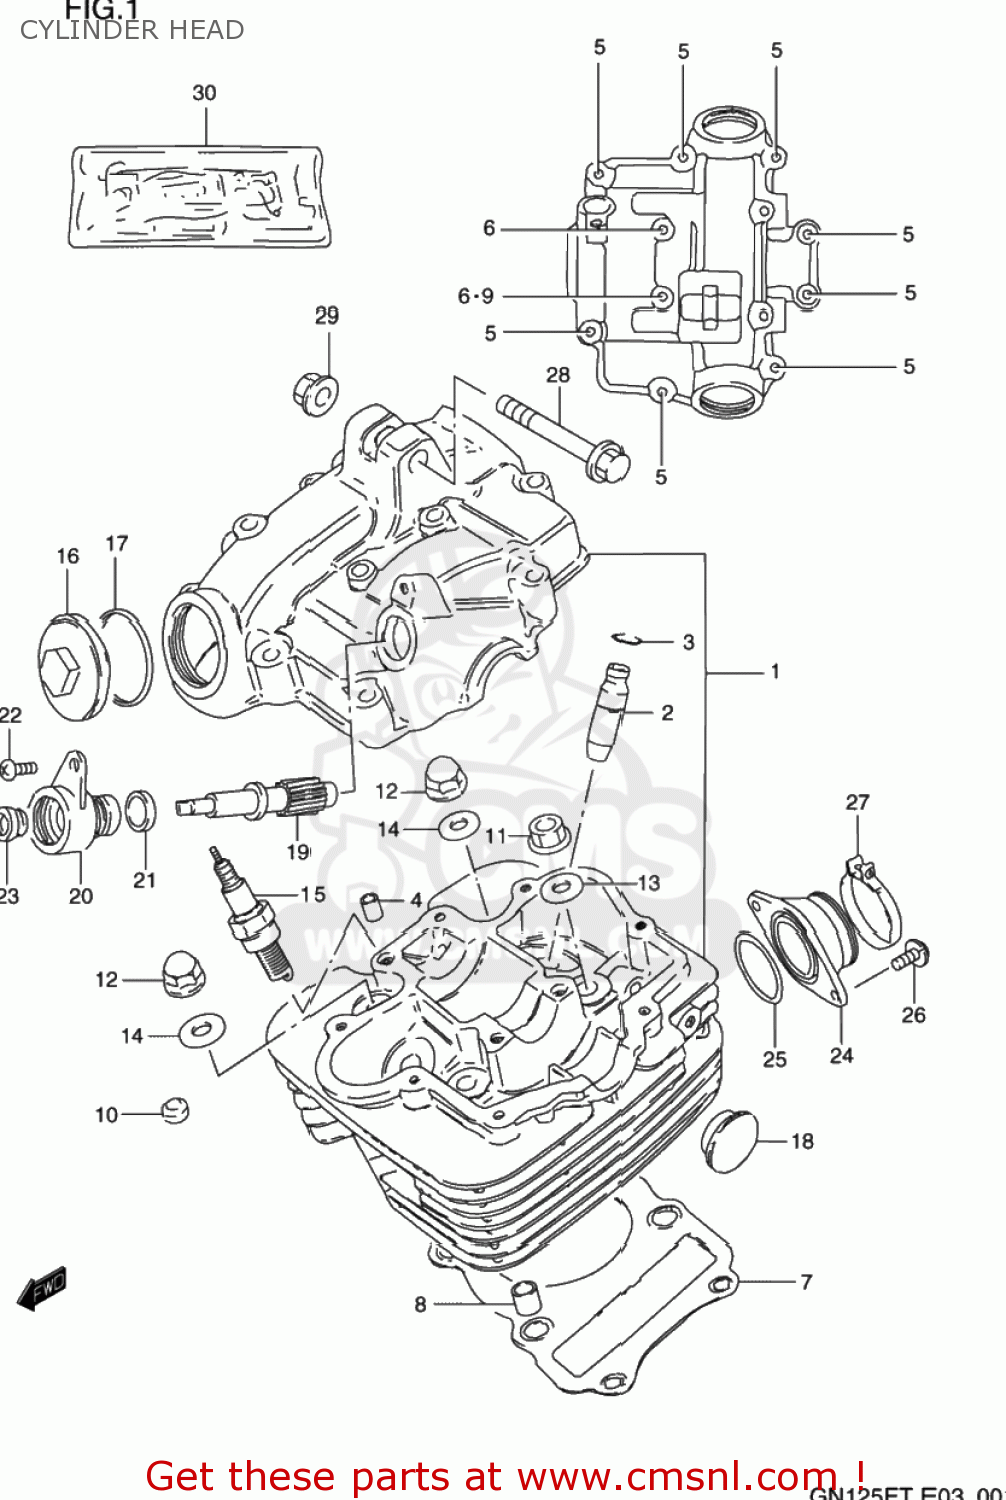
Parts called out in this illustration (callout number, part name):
1	HEAD ASSY,CYLINDER
2	GUIDE,VALVE
3	RING,SNAP
4	PIN(6.2X8X11)
5	BOLT
6	BOLT
7	GASKET,CYLINDER HEAD (NAS)
8	PIN
9	GASKET(5.8X13X1.2) (NAS)
10	PAD,CYLINDER HEAD
11	NUT
12	NUT
13	WASHER(8.5X19X2.3)
14	GASKET (NAS)
15	SPARK PLUG D8EA
16	CAP,INSPECTION HOLE
17	O RING(D:3,ID:29.5)
18	PLUG(OD:22.5)
19	GEAR,TACHOMETER DRIVEN
20	SLEEVE,TACHOMETER DRIVE GEAR
21	SEAL,TACHOMETER DRIVEN
22	SCREW(5X12)
23	SEAL,OIL(5X12X8)
24	PIPE,INTAKE
25	O RING(D:2.4,ID:31.7)
26	SCREW
27	CLAMP
28	BOLT(8X50)
29	NUT
30	GASKET SET (NAS)
